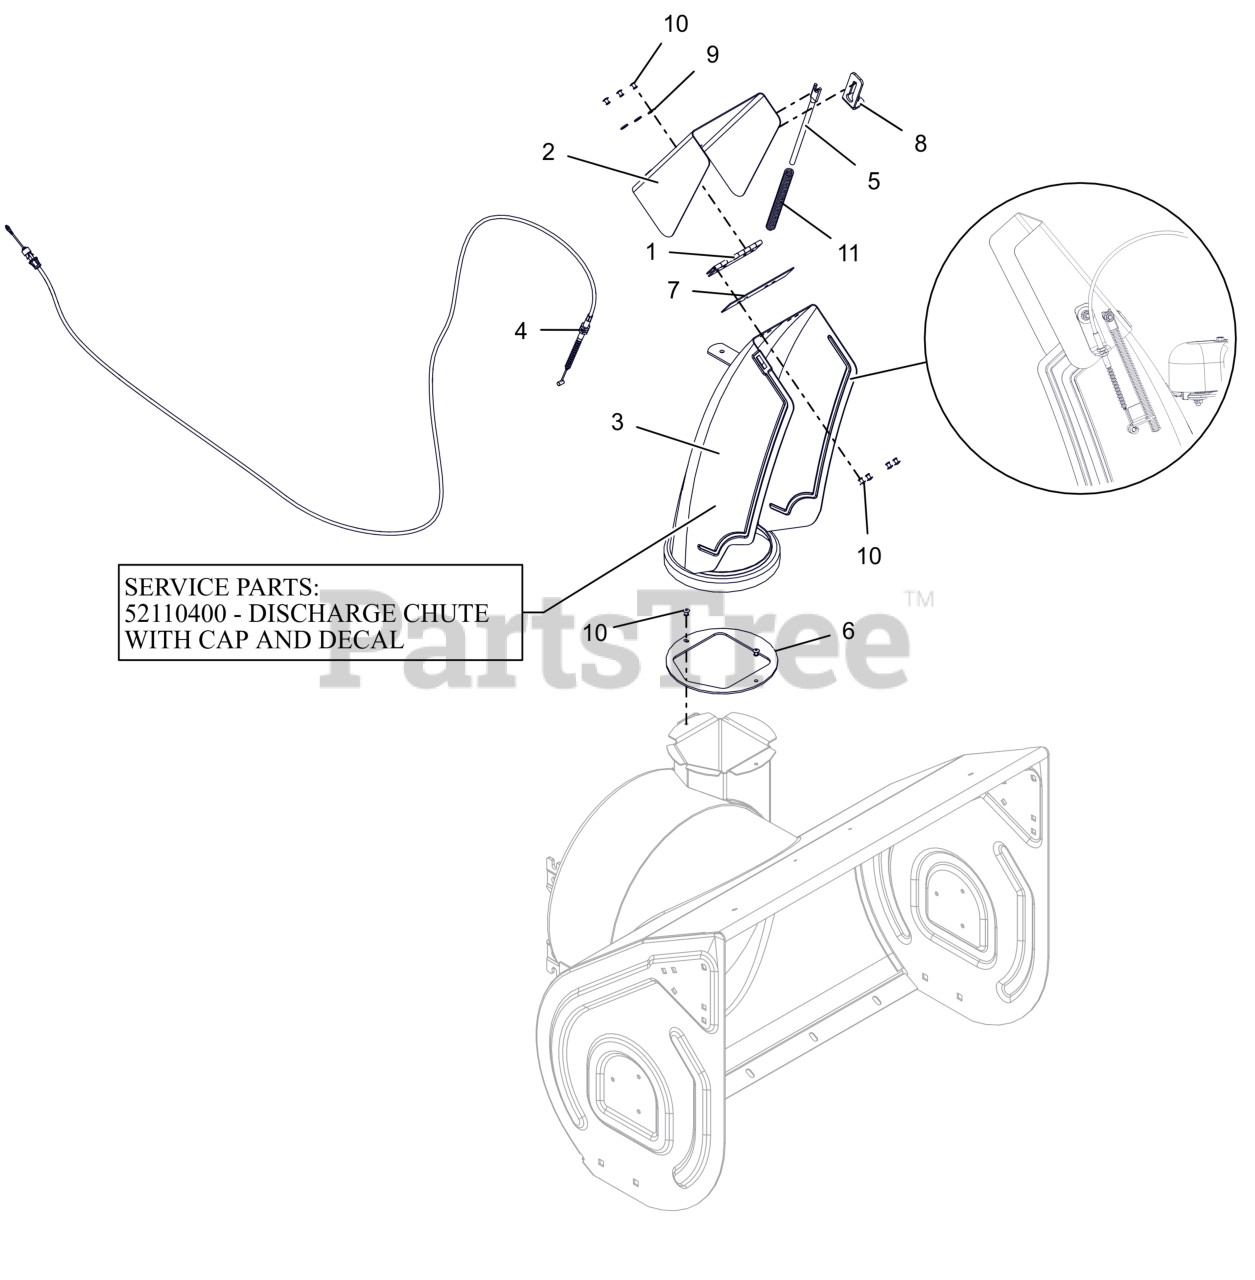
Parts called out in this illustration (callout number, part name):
2	CAP, LARGE REMOTE W/DECAL
3	CHUTE,DISCHARGE,NOTCHED,QT
3	CHUTE, DISCHARGE W/CAP
4	CABLE, DEFLECTOR - DELUXE
5	ROD, DEFLECTOR CAP
6	BAFFLE, DISCHARGE NECK
7	CAP SEAL 5.50
8	BRACKET, ANCHOR-CHUTE CABLE
9	WSHR,FLT .196X.500X.066 ZCC
10	RVT, POP .1875 ZCC
11	SG-COMP .08X.40X6.50 14#/IN
